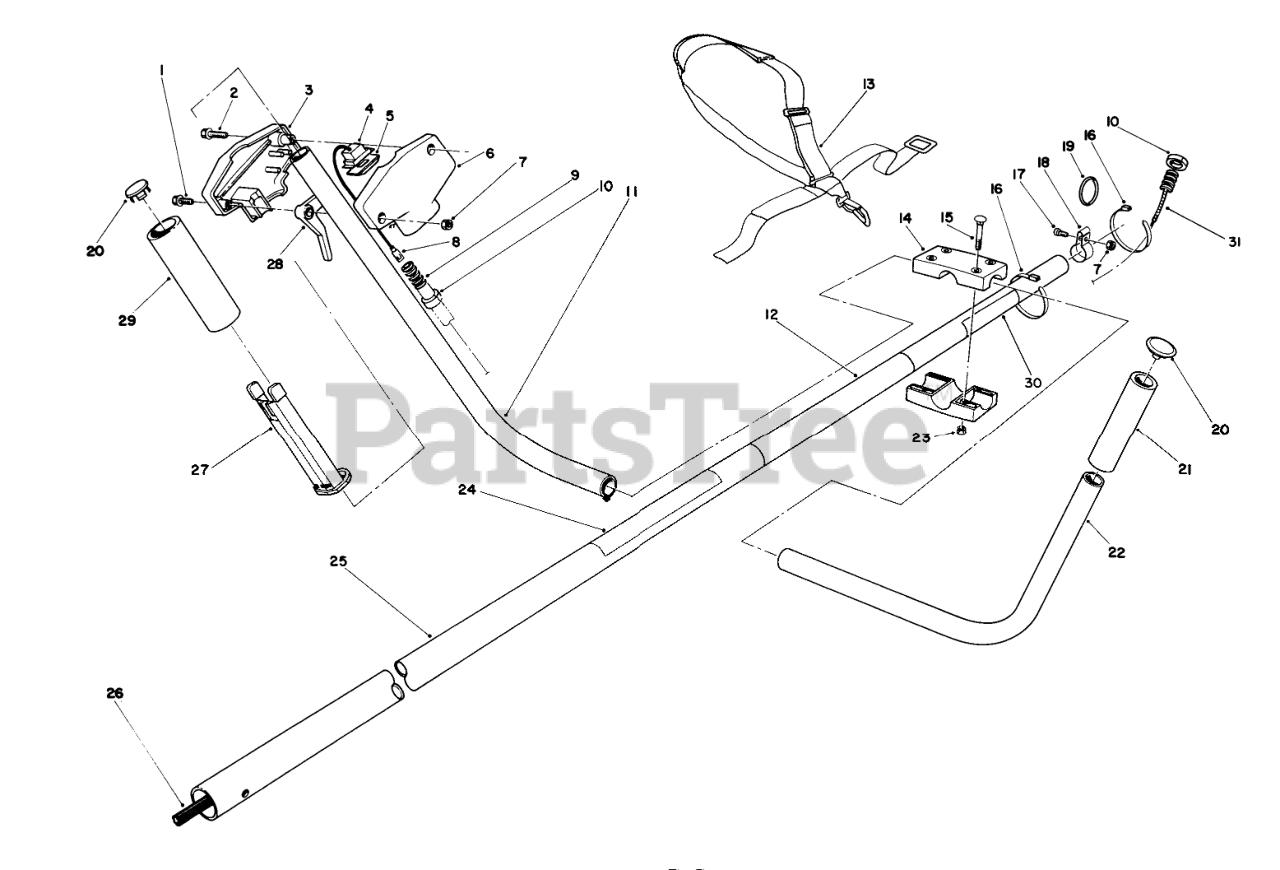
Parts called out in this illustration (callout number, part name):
1	SCREW-HWH
3	THROTTLE HSG R H 1"
4	SWITCH
5	SWITCH COVER-BLACK
6	THROTTLE HSG L H 1"
7	NUT-LOCK, NI
8	WIRE ASM
9	Cover-Cable
10	RING FITTING
11	RH HANDLE
12	DECAL - WARNING
13	Deluxe Harness
14	CLAMP
15	SCREW-CARR
16	TIE-CABLE
17	SCREW-SRH
18	HARNESS CLAMP
19	RING-HARNESS
20	TUBE CLOSURE
21	FOAM GRIP
22	LH HANDLE
23	NUT-LOCK, NI
24	Decal-TC 5010
25	TUBE ASM
26	SPLINE SHAFT
27	TROUGH
28	THROTTLE LEVER
29	GRIP-RUBBER
30	DECAL-INSTRUCTION
31	THROTTLE CABLE
